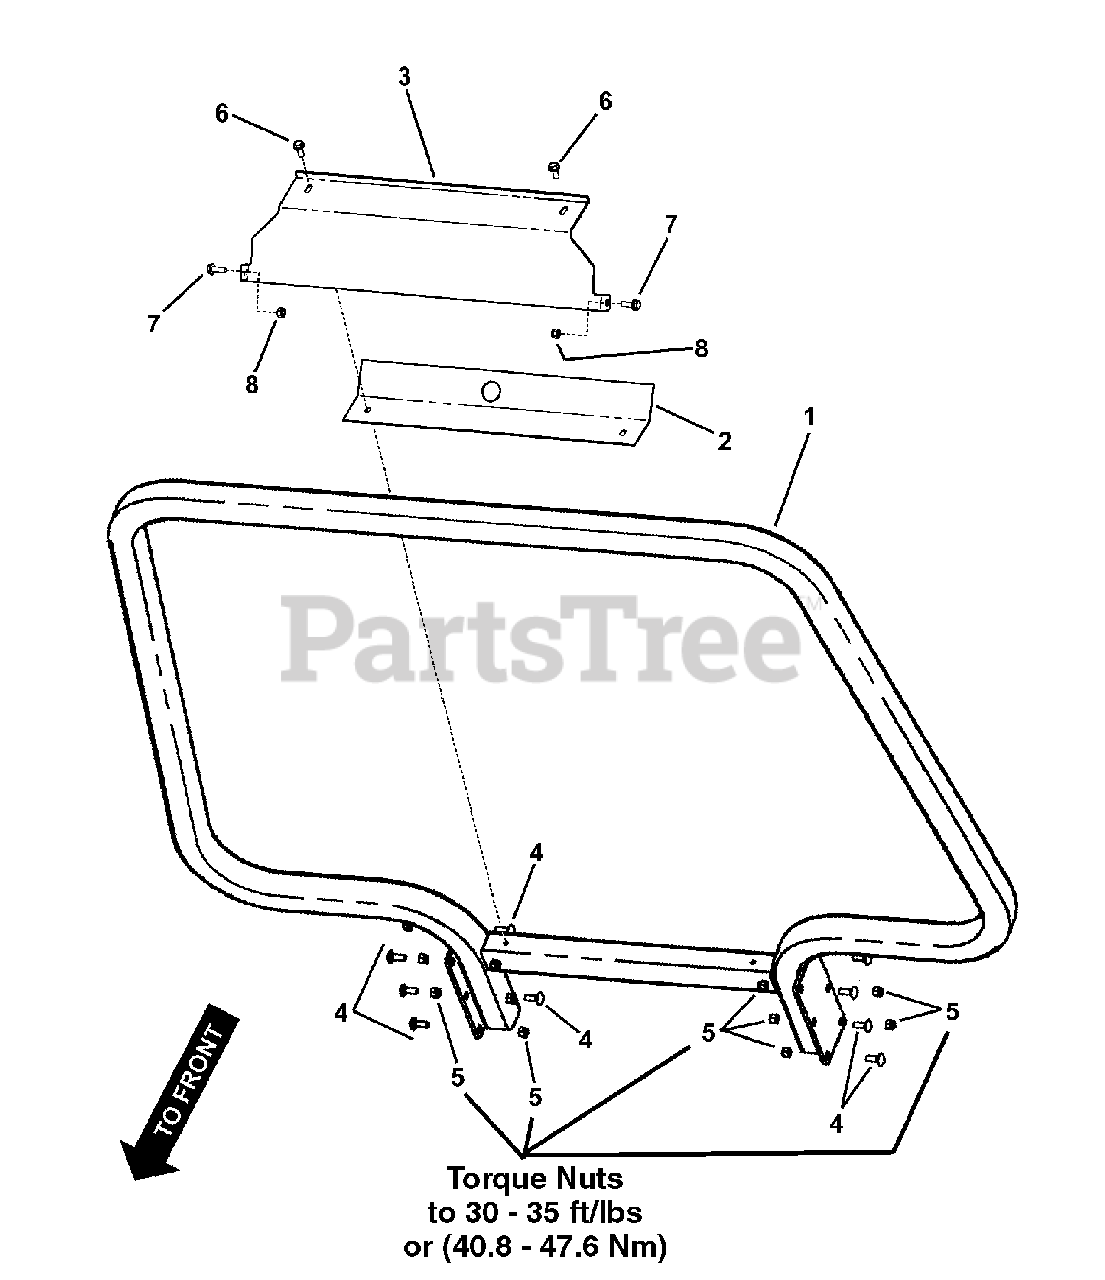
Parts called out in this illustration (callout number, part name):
1	ROPS ASSEMBLY
2	HEAT SHIELD, Cab (UV-2)
3	SHIELD, Heat/Debris, Used on Turf Cruiser Models 85632 & 85668
3	SHIELD, Heat/Debris, Used on Trail Cruiser Model 85903
4	CARRIAGE BOLT, 3/8-16 x 1 GR 5
5	NUT, Hex Nyloc, 3/8-16
6	SCREW, Hex Washer Self-Tap, 5/16-18 x 3/4
7	BOLT, Hex Flange Lock, 5/16-18 x 7/8
8	NUT, Hex Nyloc, 5/16-18
